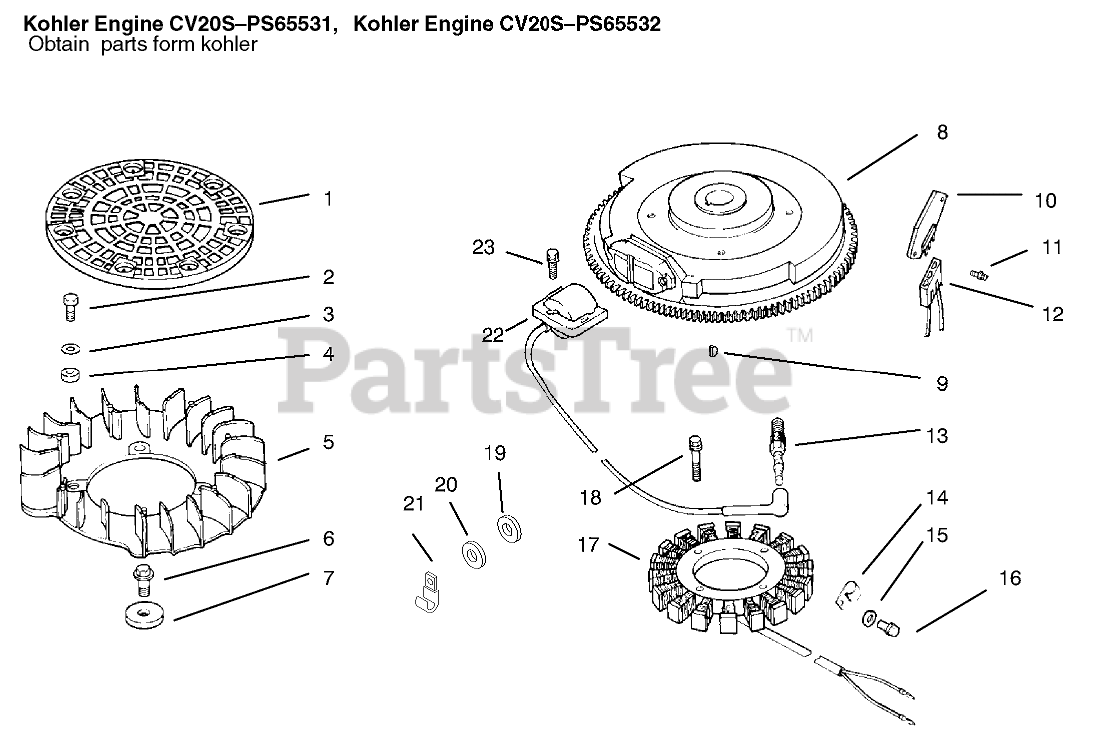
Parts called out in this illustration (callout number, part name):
1	Screen-Grass
3	Washer
4	Spacer-Fan
5	Fan
6	Screw
7	Spacer
8	Flywheel
9	Key
10	Rectifier-Regulator
11	Screw
12	Connector
13	Plug-Spark
14	Clip
15	Washer
16	Screw
17	Stator-15 Amp
18	Screw
19	Washer
20	Washer
21	Clip
22	Module-Ignition
